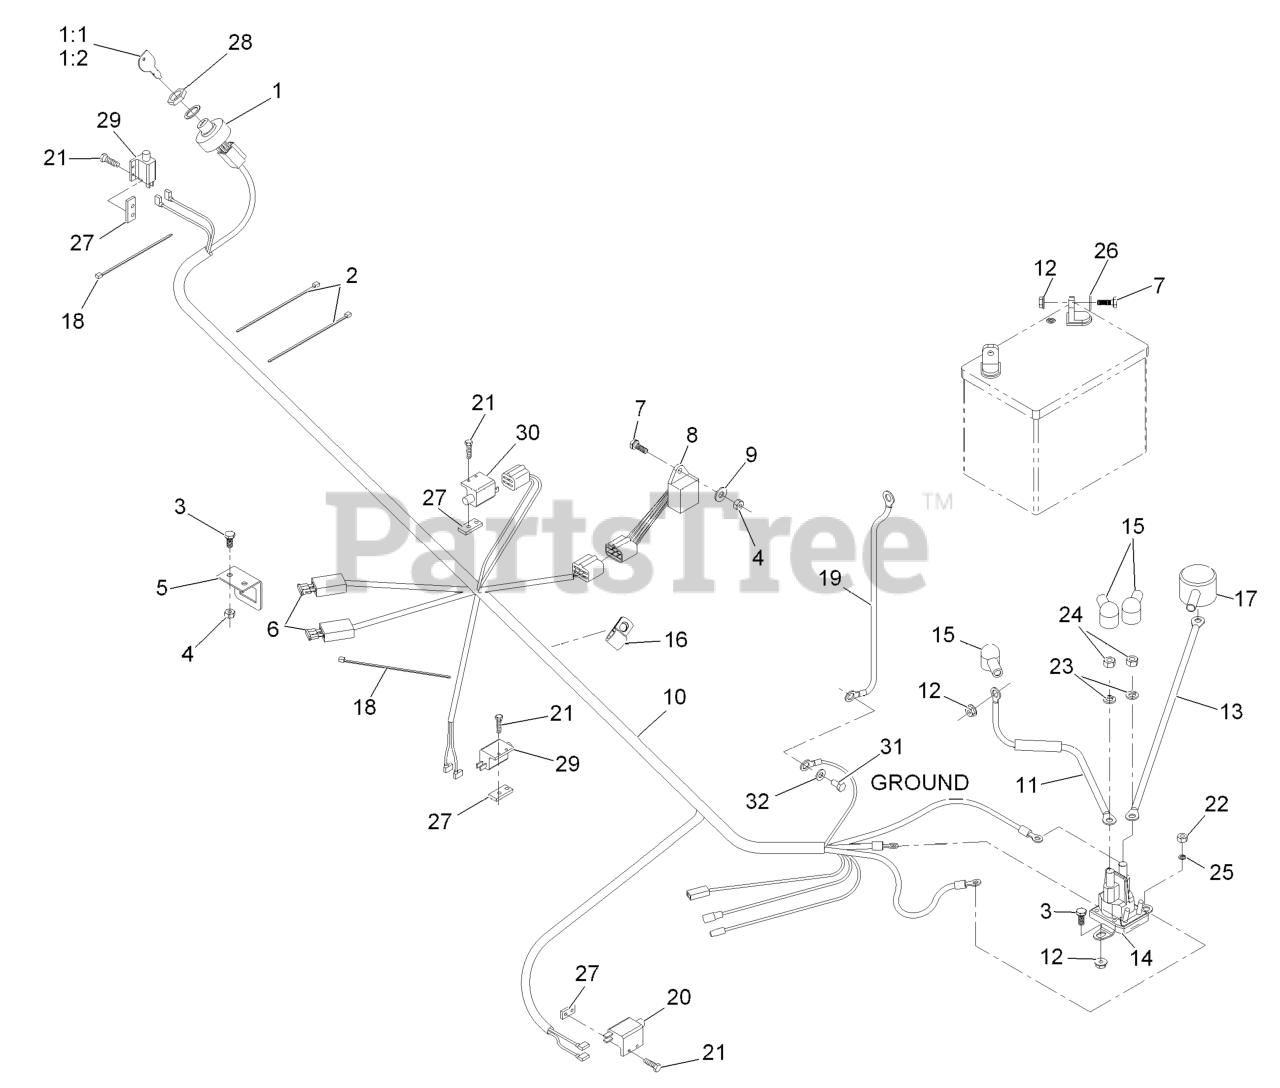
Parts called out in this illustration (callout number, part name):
1	SWITCH,IGNITION
1:1	KEYS-IGNITION (SPARE PAIR
1:2	KEY-IGNITION
2	TIE-PLASTIC
3	SCREW-HH
4	NUT-LOCK, NI
5	BRACKET,FUSE
6	FUSE-BLADE TYPE, 20 AMP
7	SCREW-HH
8	MODULE-OPC NO TIME DELAY
9	WASHER-FLAT
10	HARNESS,WIRING ELEC ST
11	Positive Starter Cable Asm
13	ASM,POSITIVE BATTERY CABL
14	SOLENOID
15	INSULATOR-SOLENOID
16	CLIP-LOOM
17	INSULATOR-BATTERY
18	TIE-CABLE
19	CABLE-BATTERY, NEGATIVE
20	SWITCH-CLOSED, NORMALLY
21	SCREW-PPH
22	NUT-HEX
23	WASHER-LOCK
24	NUT-JAM
25	WASHER-LOCK
26	WASHER-FLAT
27	PLATE-TAPPED
28	NUT-SWITCH, IGNITION
29	SWITCH-OPEN, NORMALLY
31	SCREW-HH
32	WASHER-PLAIN
